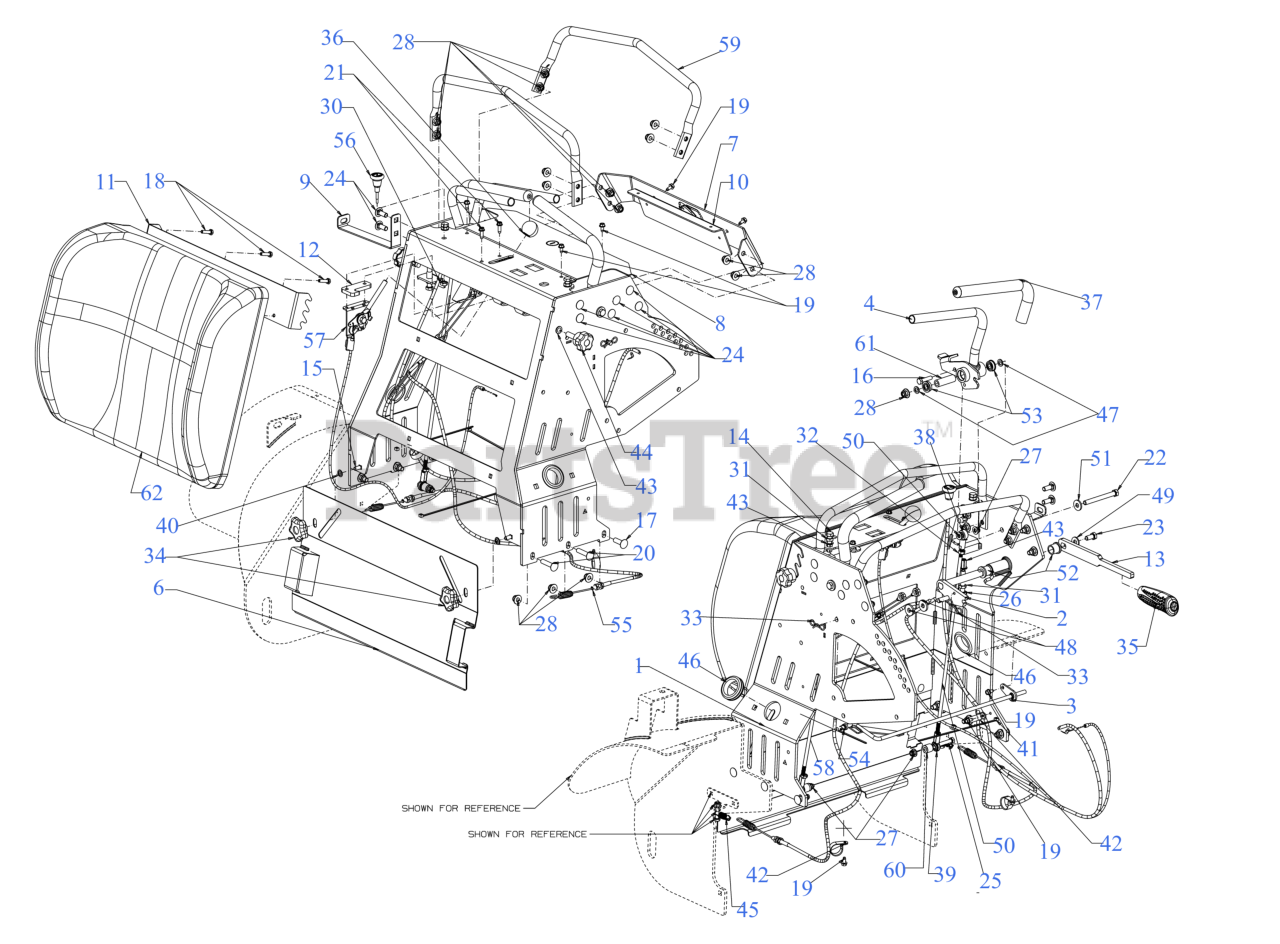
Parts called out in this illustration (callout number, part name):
1	CONTROL BASE
2	BRAKE PIVOT
3	CONTROL LOCK ROD
4	CONTROL HANDLE (LH)
4	CONTROL HANDLE (RH)
6	PANEL COVER
7	BASE CONTROL
8	DASH PANEL
9	TANK SUPPORT BRACKET
10	DASH SUPPORT
11	PAD MOUNT
12	THROTTLE STOP SPACER
13	BRAKE HANDLE
14	HEX SCREW 3/8-16 x 1.50 GR5
15	CARRIAGE BOLT 5/16-18 x .75
16	SCREW 5/16-18 x 1.25 GR5
17	CARRIAGE BOLT 3/8-16 X1.25 GR5
18	SCREW 1/4-20 X1.00 GR5
19	SCREW 1/4-20 X.500
20	BOLT 3/8-16 x 1.69 GR5
21	SCREW 1/4-20 x .750
22	SCREW 3/8-16 x 3.50 GR5
23	SCREW 3/8-16 x .75 GR 5
24	CARRIAGE BOLT 3/8-16 x 1.00 GR5
25	SCREW 5/16-18 x 1.75 GR5
26	SCREW 3/8-16 x 2 GR5
27	FLANGE LOCK NUT 5/16-18
29	HEX JAM NUT 5/16-24 GR5
30	HEX JAM NUT 3/8X24
31	HEX JAM NUT 3/18-16
32	NUT-5/16X 24
33	PIN:COTTER
34	STAR KNOB 5/16-18
37	GRIP .75 ID X 1.00 OD
38	ROD END 5/16 ID
39	END ROD- 5/16 (LH)
41	TIE CABLE 8.5 LG
42	DRAIN HOSE CLAMP
43	RIV NUT 3/8-16
44	SEAT ADJUST KNOB 3/8-16 x 1.50
45	EXTENSION SPRING .500 OD x 1.71
46	RUBBER GROMMET (1.50X2.13X.563)
47	FLAT WASHER
48	FLAT WASHER .385 x 1.00 x .135
49	FLAT WASHER .385X.870X.090
50	FLAT WASHER
52	FLANGE BEARING
53	FLANGE BEARING
54	BUSHING .3135ID
55	BRAKE CABLE
56	CHOKE CABLE
57	THROTTLE CABLE
58	CONTROL ROD
59	TUBE
60	SPACER .34 x .75 x .63 LG
61	SPACER .379 x .63 x 1.957
